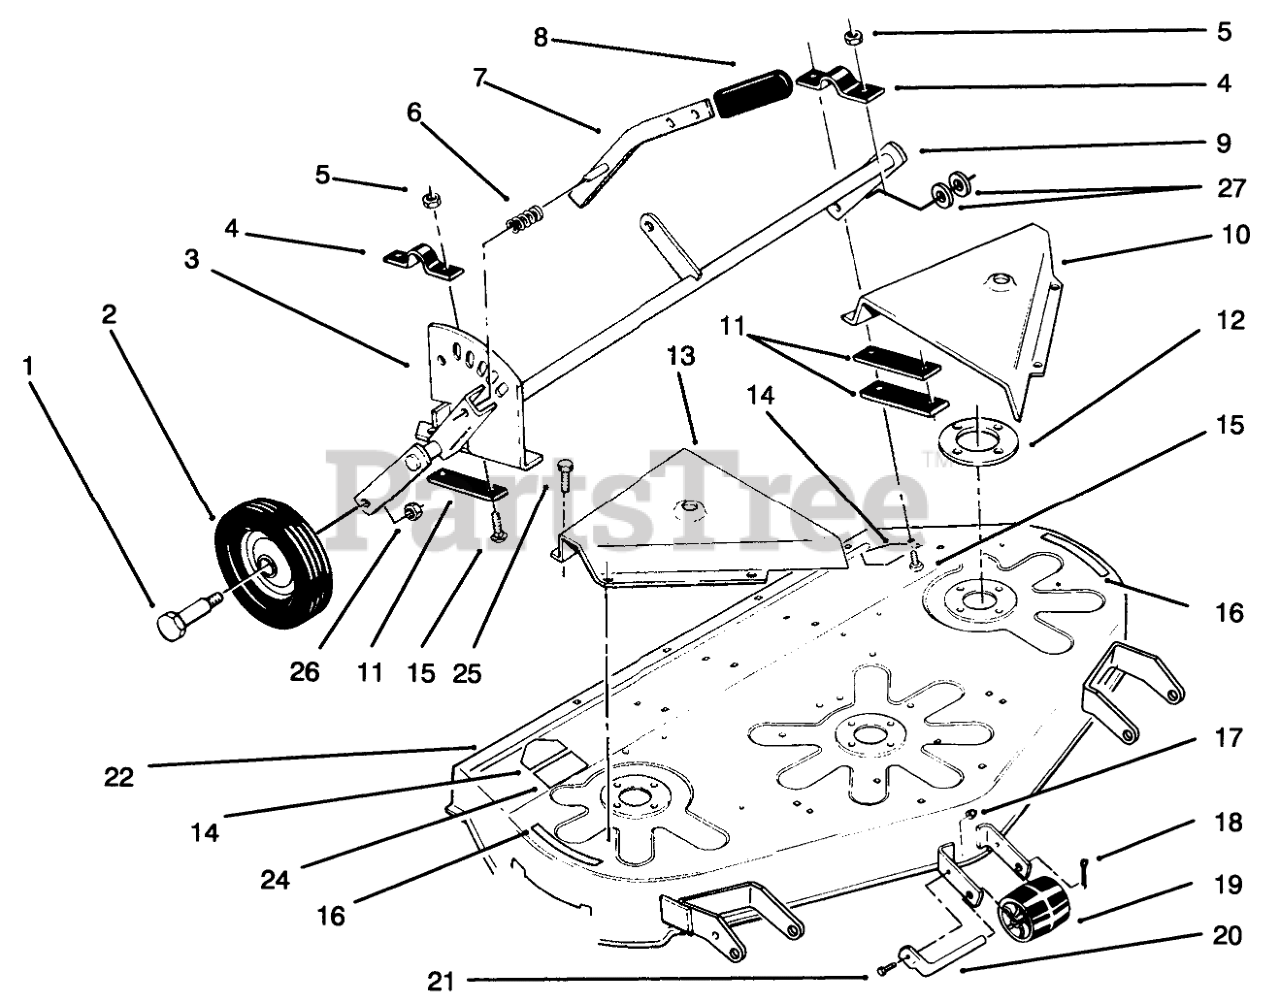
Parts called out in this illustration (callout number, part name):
1	BOLT-SHOULDER
2	WHEEL
3	Quadrant
5	NUT-LOCK, NI
6	SPRING-COMPRESSION
7	Lever
9	Gauge-Wheel Support
10	Belt Cover LH
11	Bar
12	PLATE-SPINDLE
13	Belt Cover RH
14	DECAL-DANGER
15	BOLT-CARR
16	DECAL - DANGER
17	NUT-LOCK, NI
18	PIN-COTTER
19	Roller
20	ROLLER-SHAFT
21	SCREW-HH
22	Deck-Mower (Incl. ref.# 14 & 16)
23	DECAL-42" RECYCLER
24	DECAL-HEIGHT & BELT
25	Bolt
26	NUT-HEX
